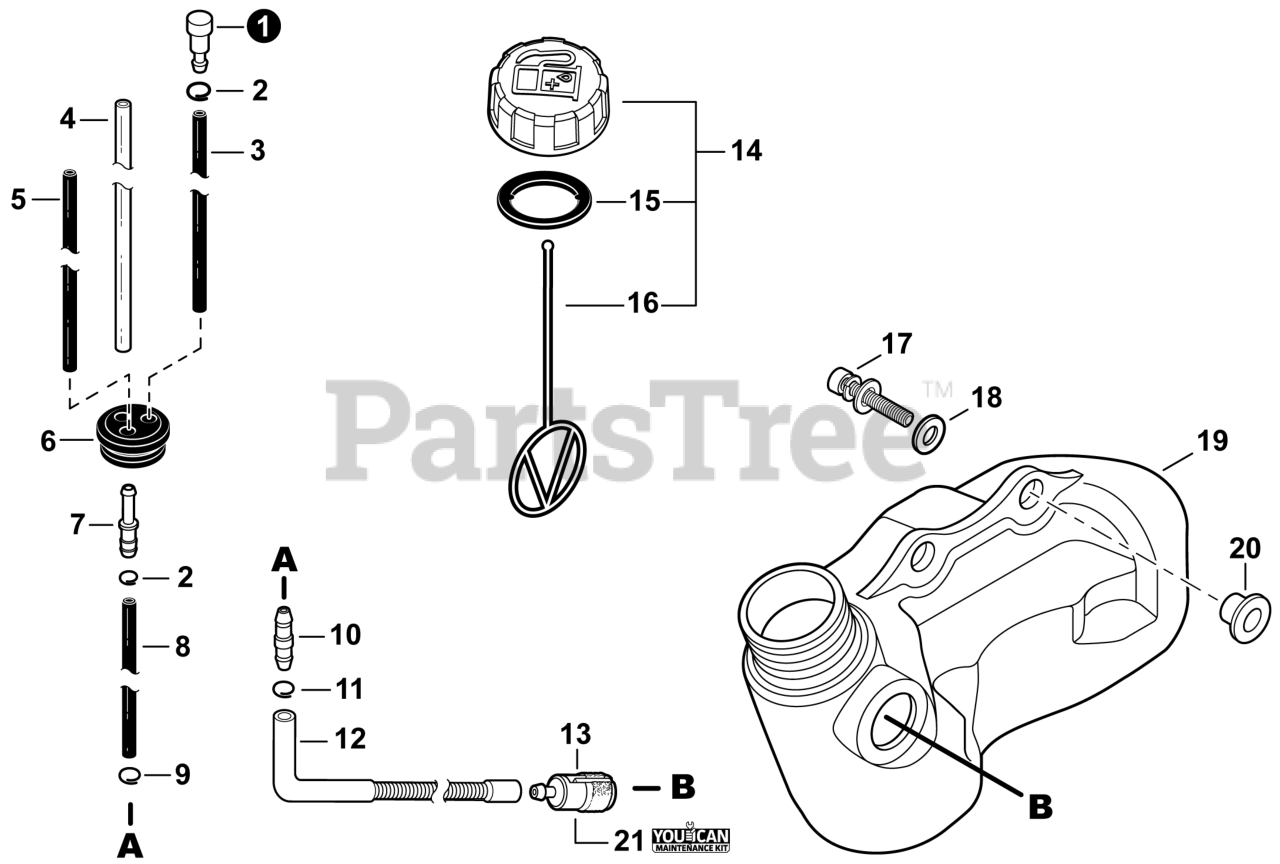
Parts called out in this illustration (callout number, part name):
1	VENT ASSY
2	CLIP Ø6.5 MM
3	PIPE, FUEL 3×6×50 BLACK
4	PIPE, FUEL 3×6×75 CLEAR
5	PIPE, FUEL 3×5.5×64 BLACK
6	GROMMET, FUEL
7	CONNECTOR, PIPE Ø5ר3.5
8	PIPE, FUEL 3×6×35 BLACK
9	CLIP Ø6
10	CONNECTOR, PIPE
11	CLIP 6.6 MM
12	PIPE, FUEL 3×7×100 FLEXIBLE
13	FILTER, FUEL
14	CAP ASSY, FUEL
15	GASKET, FUEL CAP
16	CONNECTOR, CAP L= 123
17	BOLT 5×20
18	WASHER 5.5×12×0.8
19	FUEL TANK, HC-155/165 2020
20	COLLAR 5
21	TUNE-UP KIT - YOUCANT
